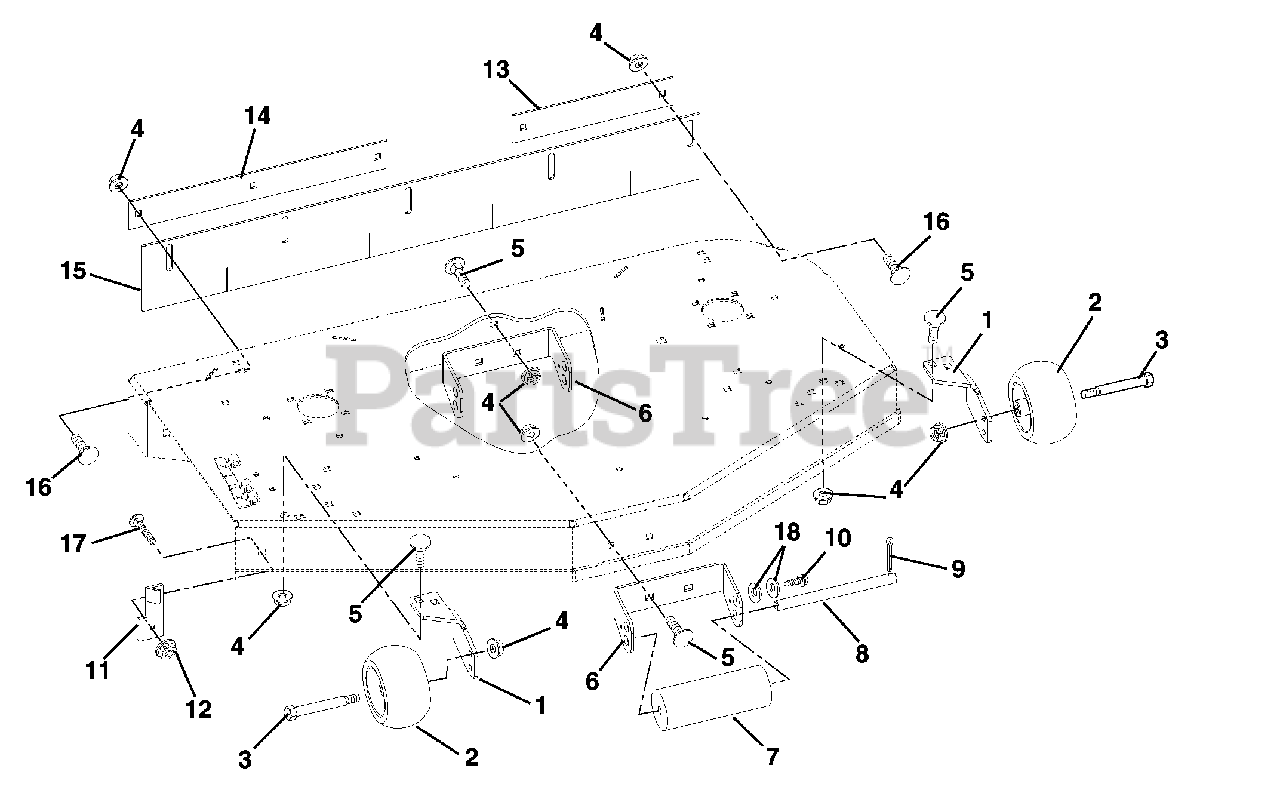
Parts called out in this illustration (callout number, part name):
1	Bracket, Anti Scalp
2	Wheel 5 x 3
3	Bolt, Shoulder .38-16 x 2.50 Hex Washer Head Grade 5
4	Nut .38-16 Flange Nyloc
5	Bolt-Round Head Square Neck .38-16 x 1.00 Grade 5
6	Bracket, Roller Mount
7	Roller
8	Pin, Retainer
9	Pin, Cotter .25 x 1.00
10	Screw, Tapping .25-20 x .50 Hex Washer Head
11	Bracket, Chute Lock
12	Nut-Flange .375-16
13	Bar, Left Hand Retainer Striper
14	Bar, Retaining Striper (044)
14	Bar, Retaining Striper (046)
14	Bar, Retaining Striper (048, 050)
15	Striper, Rubber-40" (044)
15	Striper, Rubber-44" (046)
15	Striper, Rubber-48" (048)
15	Striper, Rubber-52" (050)
16	Bolt, Round Head Square Neck .38-16 x 1.00 Grade 5
17	Bolt, Round Head Square Neck .38-16 x 1.25
18	Washer, Flat Steel .344 x .688 x .065
